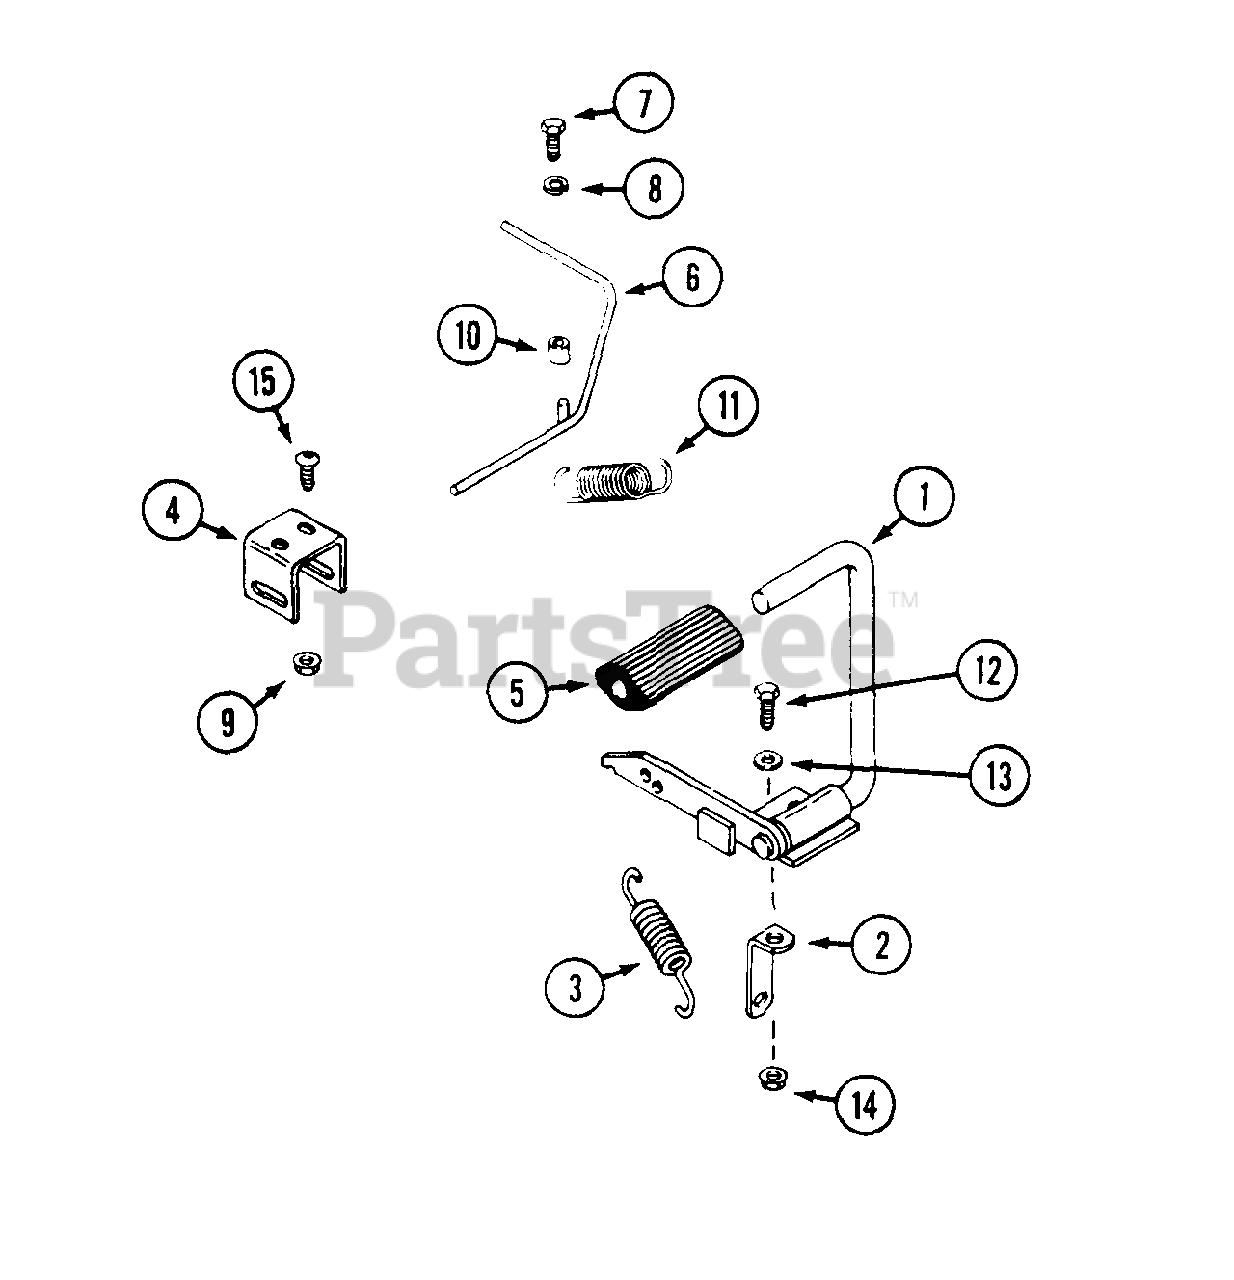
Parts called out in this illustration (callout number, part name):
1	PEDAL - parking brake
2	TAB - spring mount
3	SPRING - brake return
4	BRACKET - brack lock
5	PAD - brake pedal
6	LEVER - brake lock
7	SCREW - 5/16" - 18 x 5/8" allen head
8	LOCKWASHER - 5/16"
9	NUT - 1/4" - 20 flange lock
11	SPRING - return, lock lever
12	BOLT - 5/16" - 18 x 1"
13	WASHER - 5/16"
14	NUT - 5/16" - 18 flange lock
15	SCREW - 1/4" - 20 x 1/2" allen head
